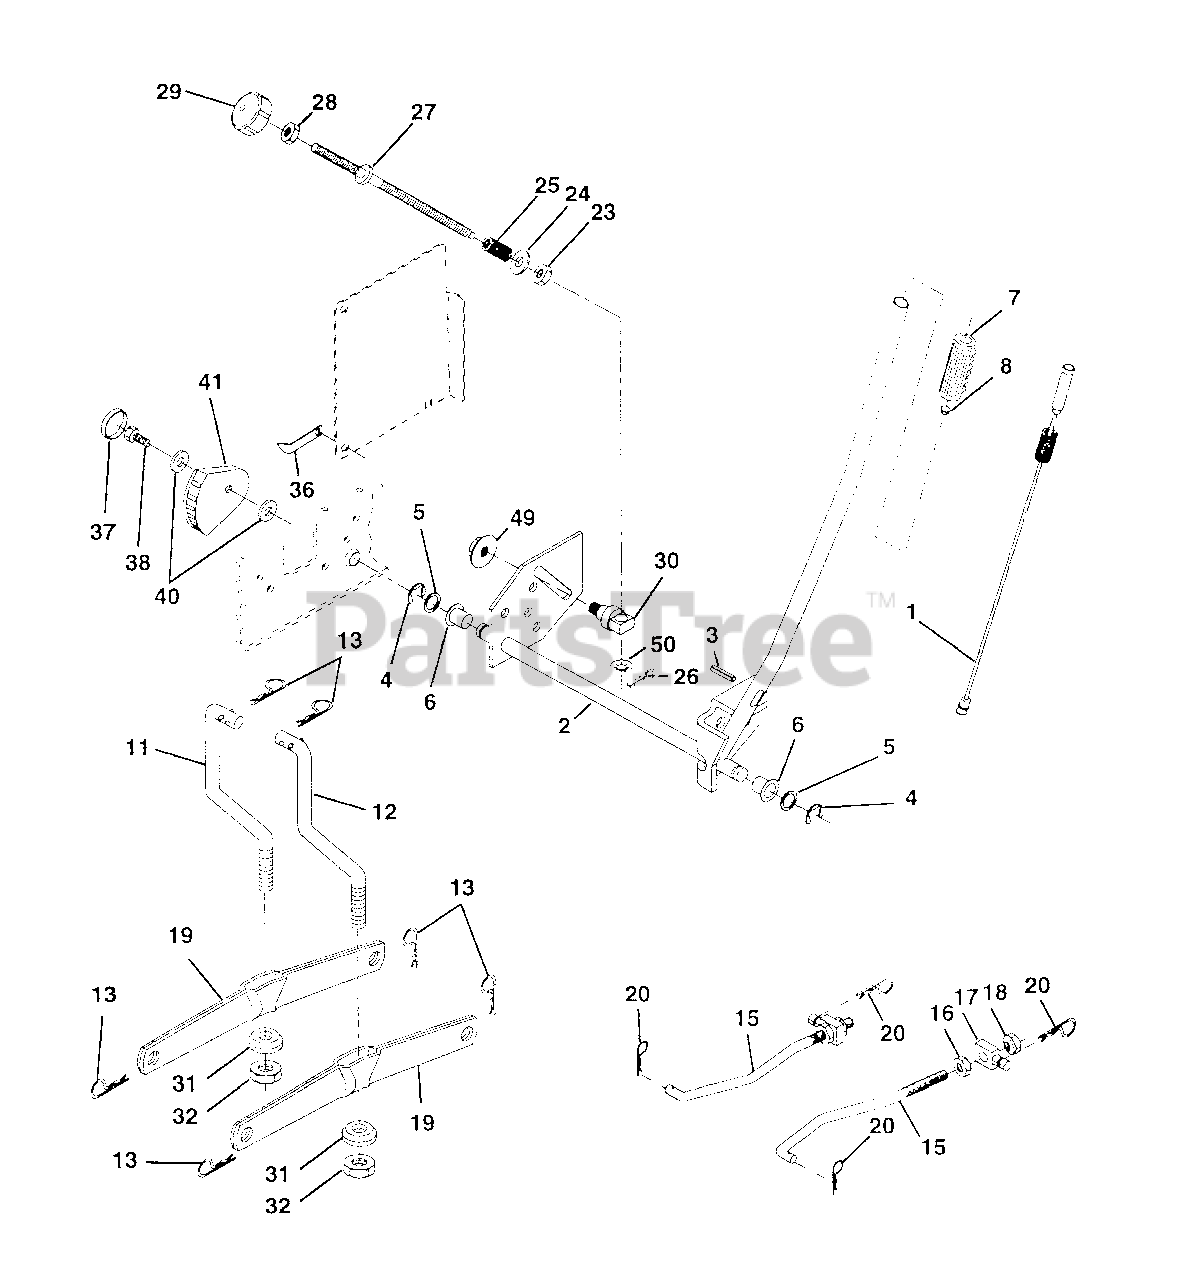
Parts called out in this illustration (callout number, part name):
1	Wire Asm Inner/Sprg w/Rlngr LT
2	Shaft Asm Lift RH w/Inf
3	Pin Groove 1 500 Zinc
4	E Ring #5133-62
5	Washer 21/32 X 1 X 21 Ga
6	Bearing Nylon Blk 629 Id
7	Grip Handle Fluted Blk
8	Button Plunger Black
11	Link Lift LH Fixed Length
12	Link Lift RH Fixed Length
13	Retainer Spring
15	Link Front
16	Nut Jam Hex 1/2-13 Unc
17	Trunnion Blk Zinc
18	Nut Lock W/wsh 1/2-13unc
19	Arm Suspension Rear
20	Retainer Spring
23	Nut Special
24	Washer 13/32 X 5/8 X 16 Ga
25	Spring 2-1/8"
26	Pin Cotter 3/32 X 1/2
27	Rod Adj Lift Zinc 7.49 Wrk Lg
28	Nut Hex Jam 3/8-16 Unc
29	Knob Inf 3/8-16 Unc Blk W/sym
30	Trunnion Infin Height
31	Bearing Pvt Lift Spherical
32	Nut Crownlock 3/8 - 24
36	Pointer Height Indicator
37	Plug Hole Blk 1.485/1.515 Dia.
38	Screw Thdrol 5/16-18 x 3/4
40	Washer 11/32 x 1-1/2 10 Ga.
41	Indicator Height STLT
49	Nut Hex Flange Lock
50	Nut Push Phos & Oil
